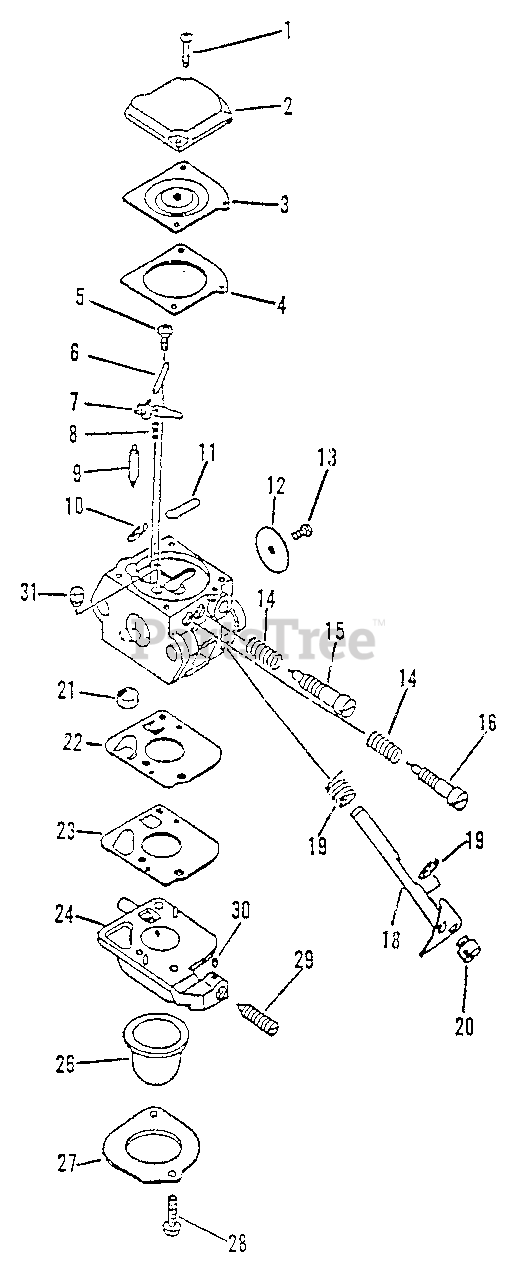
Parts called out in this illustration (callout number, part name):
2	COVER, DIAPHRAGM
3	DIAPHRAGM
4	GASKET, DIAPHRAGM
6	PIN, METERING LEVER
7	LEVER, METERING
8	SPRING
9	VALVE, NEEDLE
11	PLUG, WELCH
12	VALVE, THROTTLE
14	SPRING, NEEDLE
15	NEEDLE, HIGH SPEED
16	NEEDLE, IDLE
17	SPRING, THROTTLE RETURN
18	SHAFT, THROTTLE
21	STRAINER
22	DIAPHRAGM, PUMP
23	GASKET, PUMP
24	BODY ASSY, PURGE
26	BULB, PURGE
27	RETAINER
29	SCREW, IDLE ADJUST
30	PIECE, FRICTION
31	NOZZLE, CHECK VALVE
